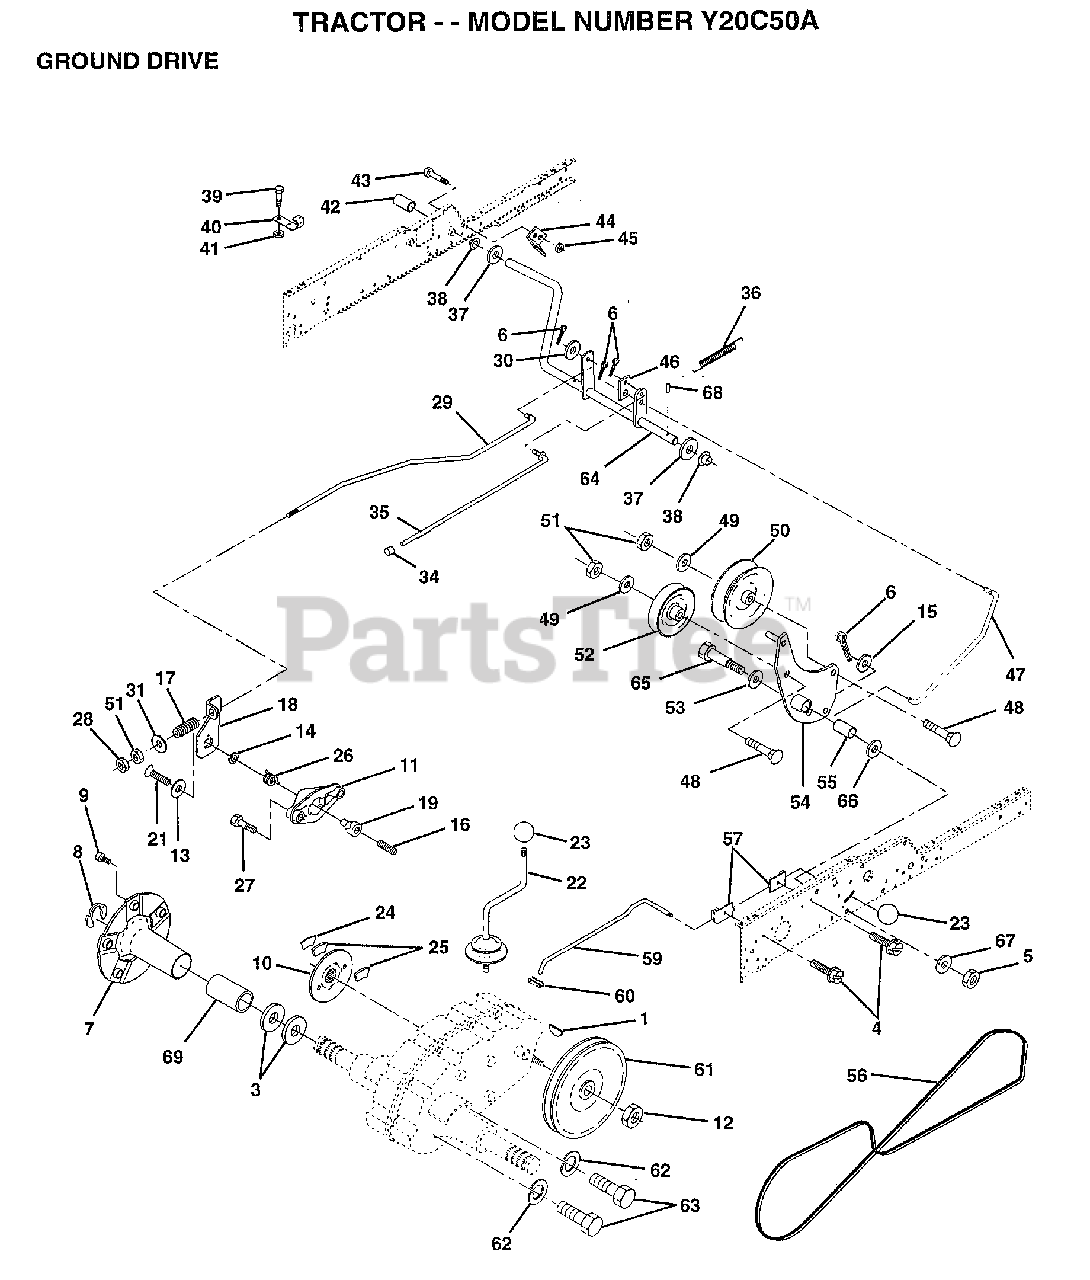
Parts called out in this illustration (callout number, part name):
3	WASHER T
4	SCREW LT
6	COTTER PIN
8	KLIP RING
9	BOLT.HUB.WHL.REAR
10	BRAKE.DISC.
11	YOKE BRAKE DISC
12	NUT STD
13	WASHER SPECIAL
14	BUSHING LEVER BKT
15	WASHER
16	SCREW SET 1/4-20
17	"SPRING,ROD BRAKE"
18	LEVER BRAKE GT
19	CAM BRAKE DISC GT
21	SCREW FLT 1/4X28
22	GEAR SHFT LVR T
23	KNOB
24	SUPPORT PUCK BRKE
25	PUCK BRAKE TOP
26	SPRING RET BRAKE
27	SCREW HX WASH
28	NUT
29	ROD BRAKE ZINC GT
30	WASHER HYT
34	PLUNGER CAP T
35	ROD BRAKE PART GT
36	SPRING DRIVE GROUND
37	WASHER
38	NYLINER T
39	SCREW
40	ACT-SWITCH T
42	PEDAL COVER T
43	BOLT LT
44	BRKT SWITCH GT
45	NUT
46	RETAINER.SPRING
47	ROD.CLUTCH
48	BOLT
49	WASHER
50	FLAT IDLER PULLEY
52	PULLEY.IDLER.V.GR
53	WASHER T
54	ARM.ASM.IDLER.CLU
55	"LY, BEARING"
56	BELTV.GR.DR.83.
57	BRACKET.ROD.SHIFT
59	ROD SHIFT HI LO
60	CONNECTING LINK
62	LOCKWASHER
63	BOLT
65	AXLE BOLT
66	WASHER.HARD.BLADE
67	WASHER
68	ROLL PIN STD
69	"COVER, HUB"
